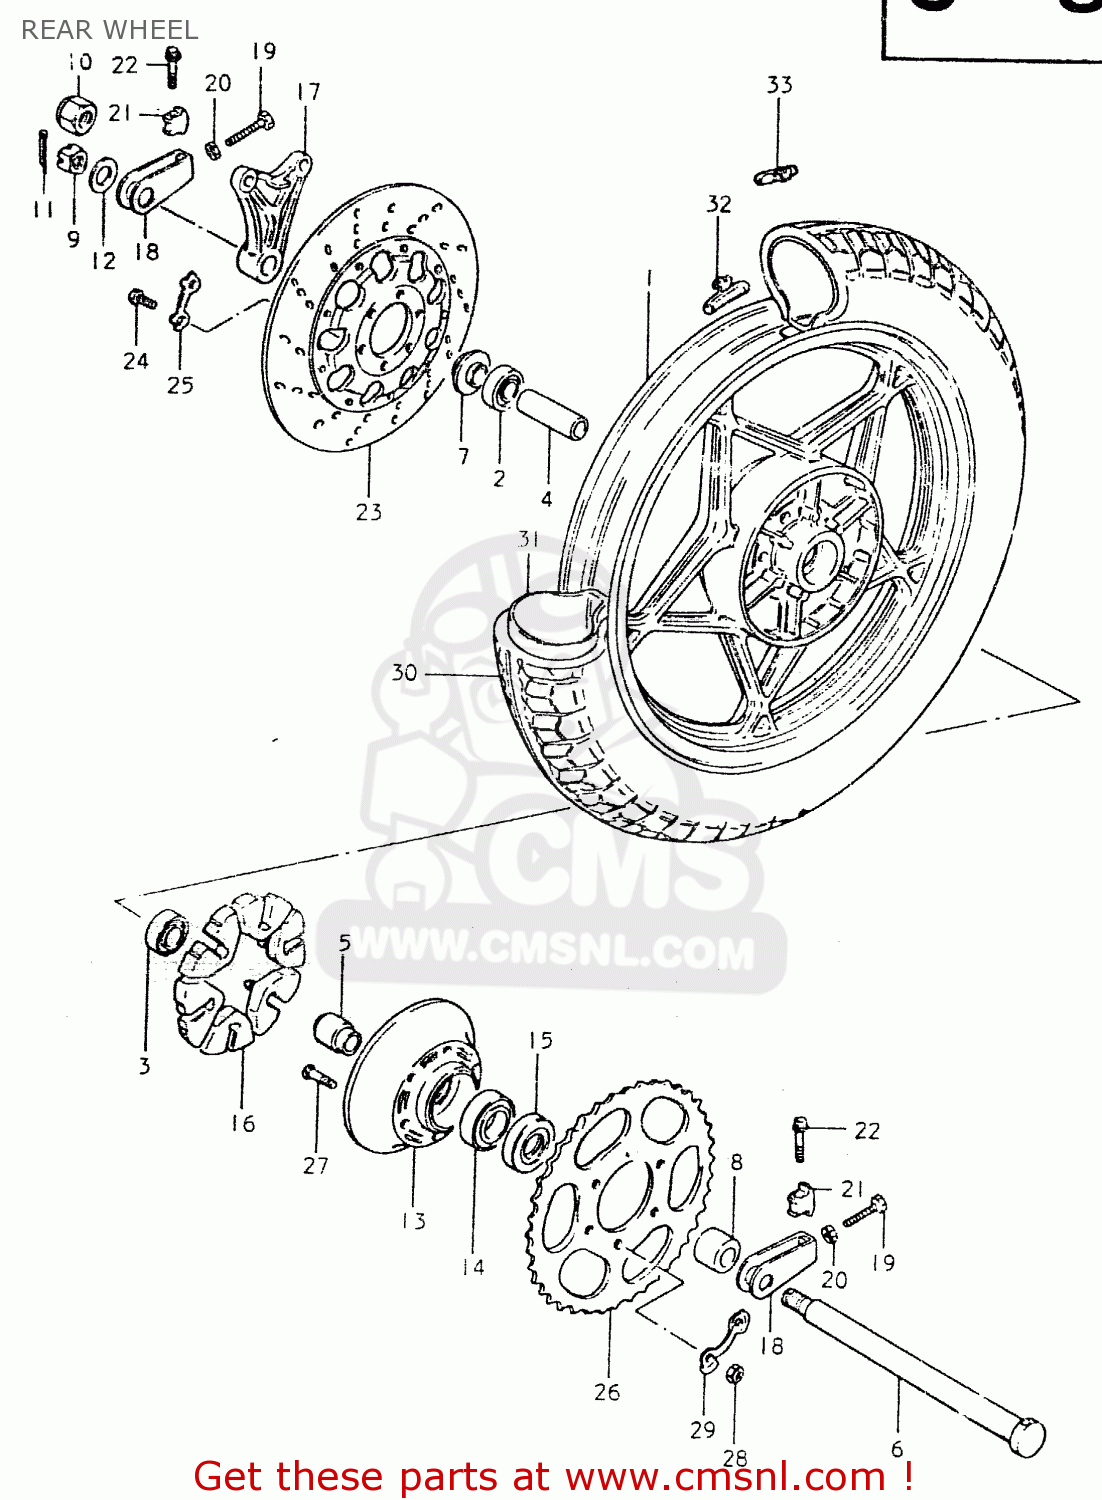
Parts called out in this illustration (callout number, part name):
1	WHEEL,REAR
2	BEARING
3	BEARING
4	SPACER(20.5X28X88)
5	RETAINER,REAR SPROCKET D
6	AXLE,REAR
7	SPACER,REAR AXLE
8	SPACER (17X33X21.1)
9	NUT
10	NUT
11	PIN,COTTER
12	WASHER
13	DRUM,REAR SPROCKET MOUNT
14	BEARING
15	SEAL,OIL(33X62X7)
16	ABSORBER,REAR HUB SHOCK
17	BRACKET,RR,CALIPER
18	ADJUSTER,CHAIN
19	BOLT 8X50
20	NUT
21	SUPPORTER,CHAIN ADJUST
22	BOLT
23	DISC,BRAKE
24	BOLT(8X30)
25	WASHER
26	SPROCKET,REAR (NT:51)
27	BOLT
28	NUT
29	WASHER
30	TIRE
31	TUBE ASSEMBLY,WHEEL,INNER
32	BALANCER,WHEEL
33	BALANCER,WHEEL
